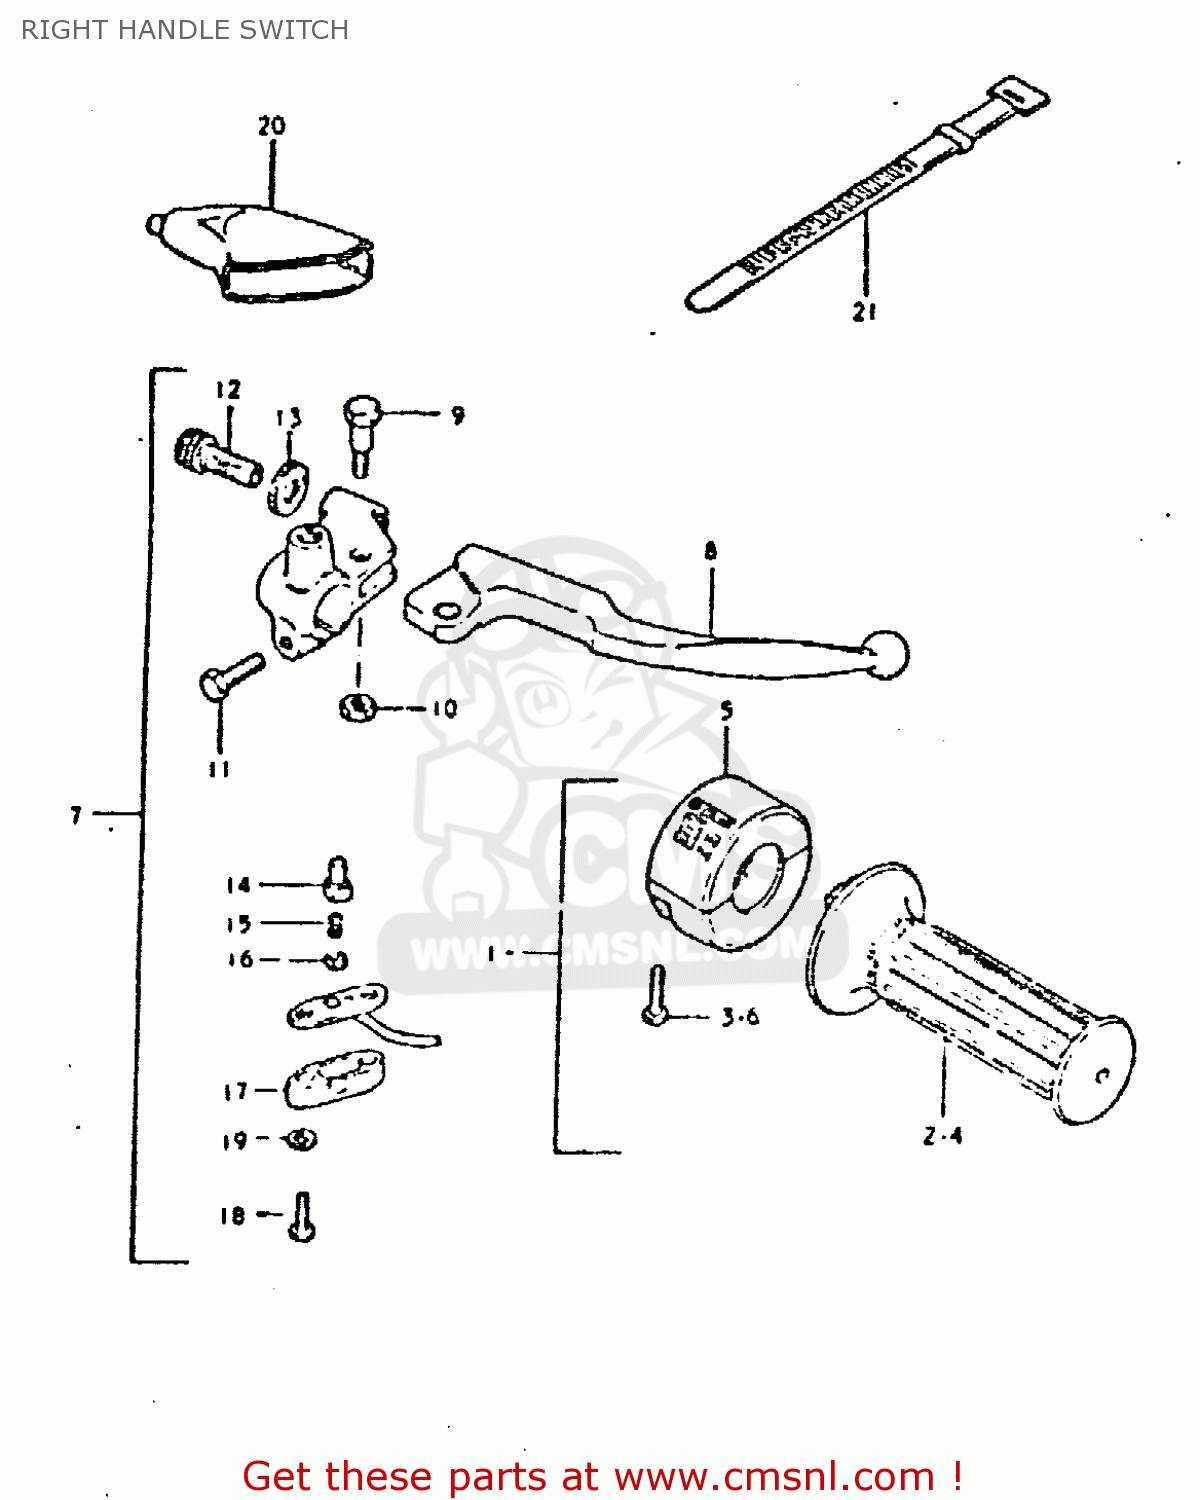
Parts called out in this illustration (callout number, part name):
1	CASE ASSEMBLY,THROTTLE
2	GRIP,THROTTLE
3	SCREW
4	GRIP,THROTTLE
5	CASE ASSEMBLY,THROTTLE
6	SCREW
7	LEVER/SWITCH ASSEMBLY,BRAKE
8	LEVER,BRAKE
9	BOLT,LEVER
10	NUT 6MM
11	BOLT
12	ADJUSTER,CABLE
13	NUT,CABLE ADJUSTER
14	HOLDER
15	SPRING
16	PLATE
17	COVER,FR BK TERMINAL BASE
18	SCREW
19	WASHER
20	COVER,CLUTCH LEVER
21	CLAMP(L:120)
